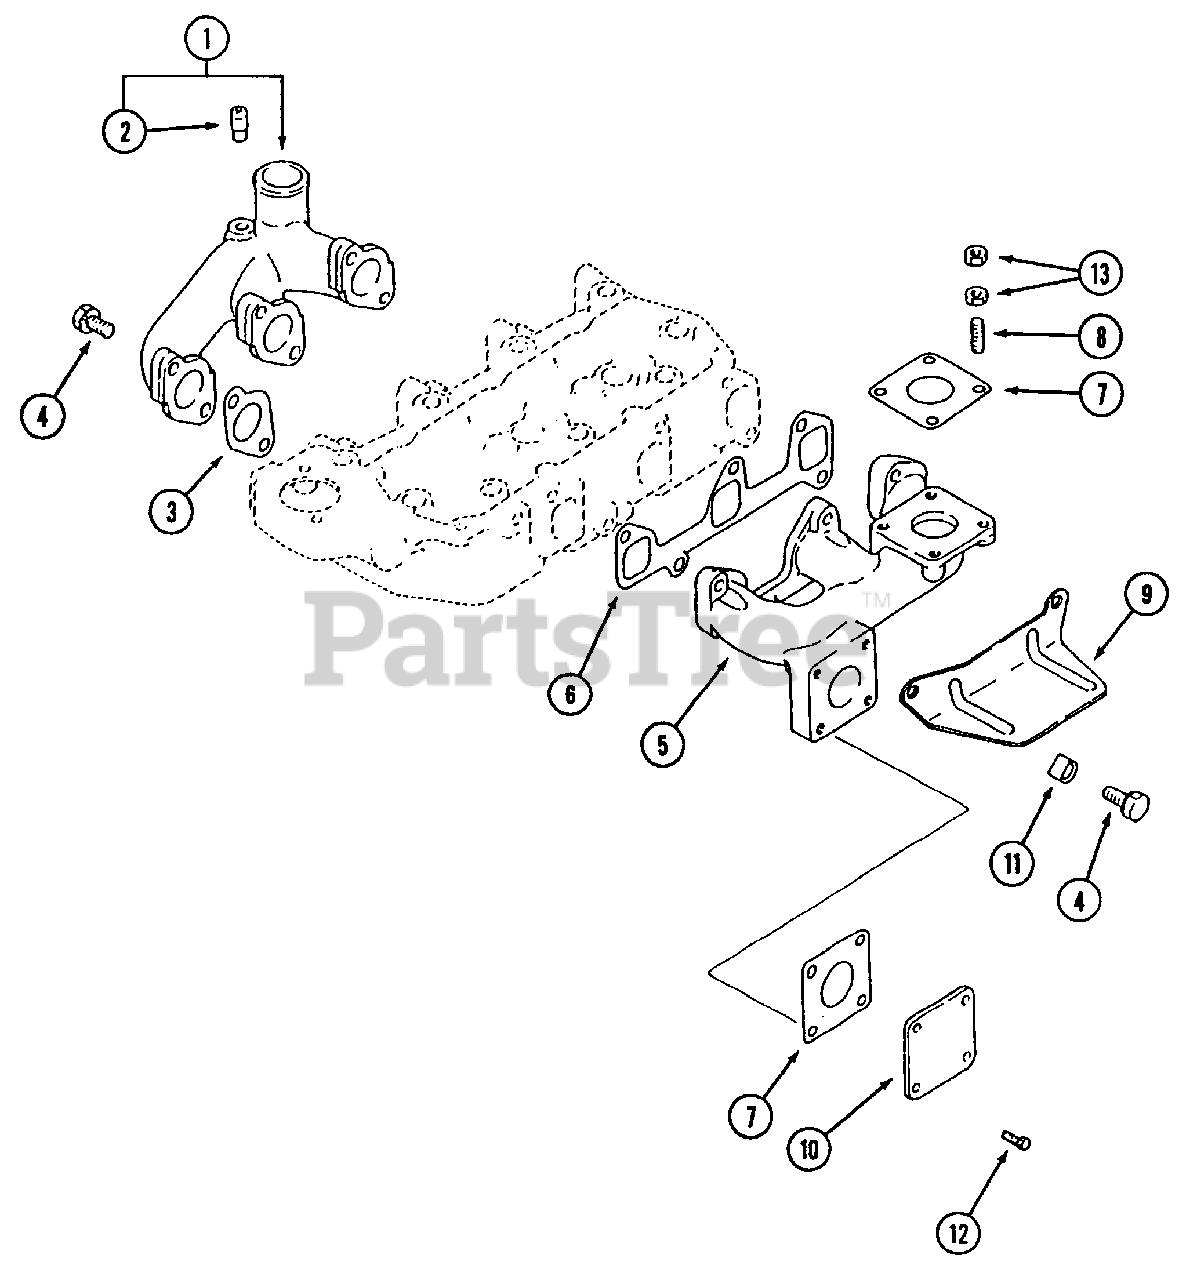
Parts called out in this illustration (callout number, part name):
1	Manifold Ass'y., Intake
2	Pipe
3	Gasket, Intake Manifold
4	Bolt
5	Manifold, Exhaust
6	Gasket, Exhaust Manifold
8	Stud
9	Cover, Starter
11	Clamp, Cable
12	Bolt
